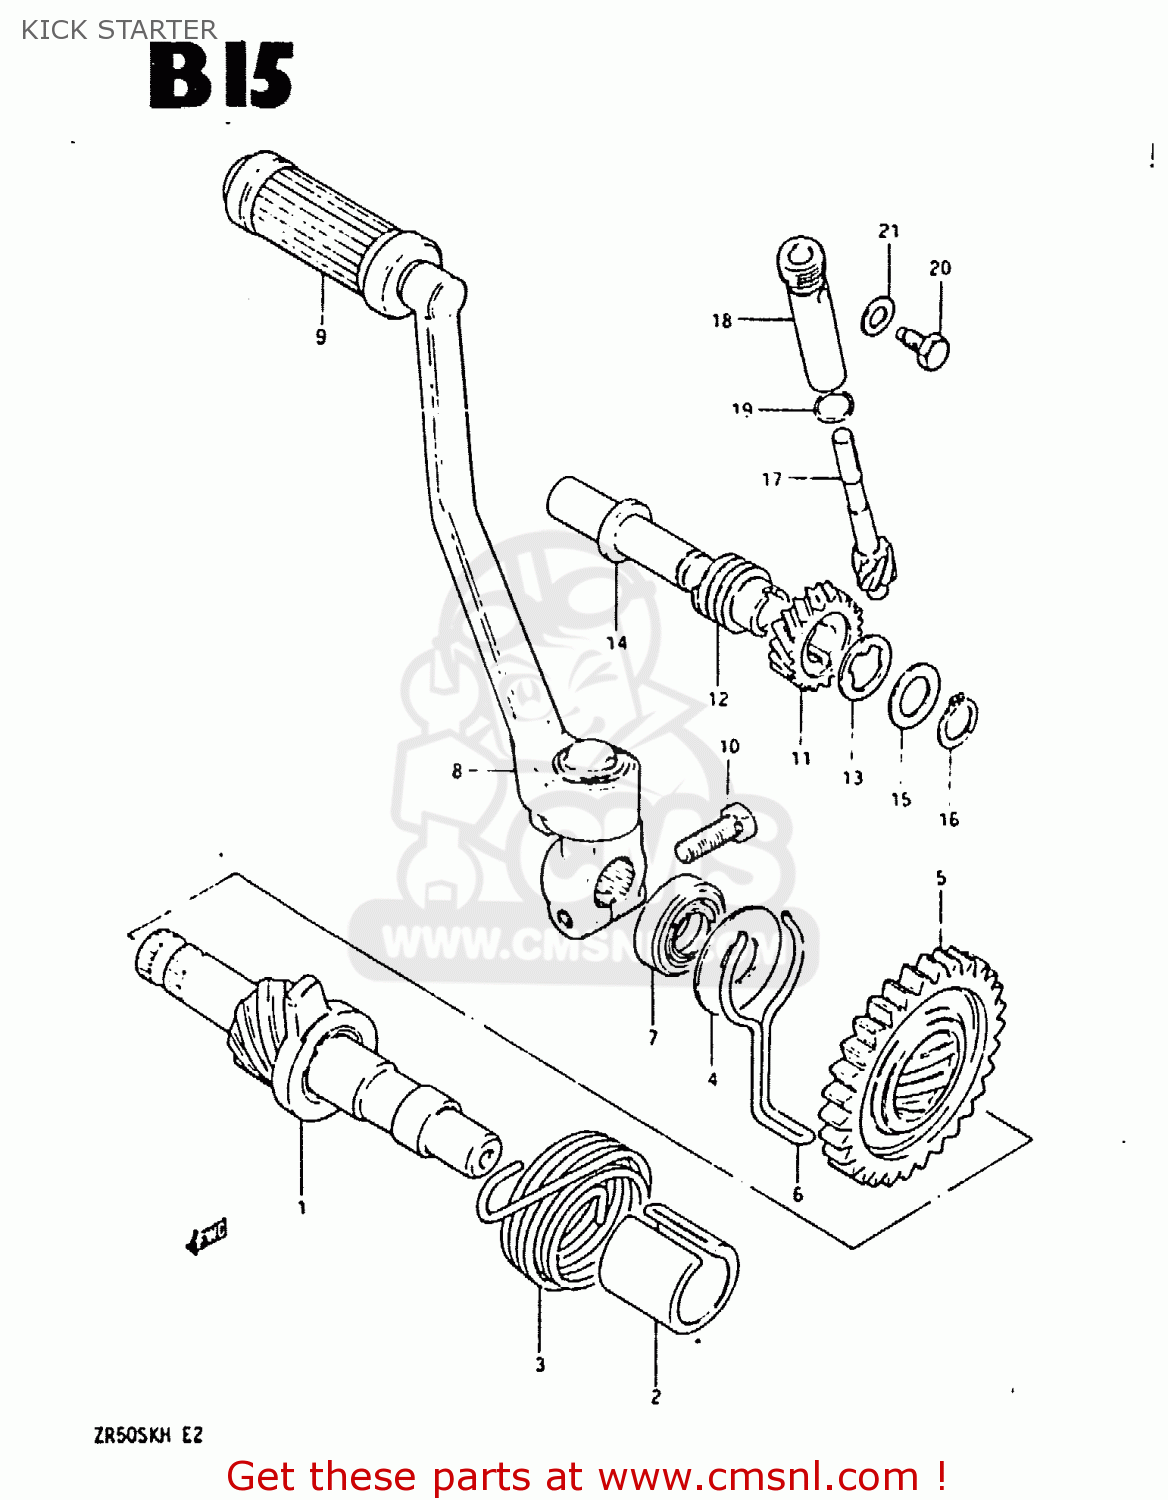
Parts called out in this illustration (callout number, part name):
1	SHAFT,KICK STARTER
2	GUIDE,KICK STARTER SFT SPRING
3	SPRING
4	WASHER
5	GEAR,KICK STARTER DRIVE(NT:30)
6	RETAINER,SNAP
7	SEAL,OIL(14X24X6)
8	LEVER ASSY, KICK STARTER
9	RUBBER,KICK STARTER PEDAL
10	BOLT
11	GEAR,TACHOMETER DRIVE(NT:19)
12	GEAR,TACH DRIVE NO.2(NT:3)
13	RETAINER,TACH DRIVEN GEAR NO1
14	SHAFT,TACHOMETER DRIVEN GEAR
15	WASHER,THRUST
16	CIRCLIP
17	GEAR,TACHOMETER DRIVEN(NT:12)
18	SLEEVE
19	O RING(D:1.3,ID:9.6)
20	BOLT
21	GASKET(6.2X11X1).2 (NAS)
